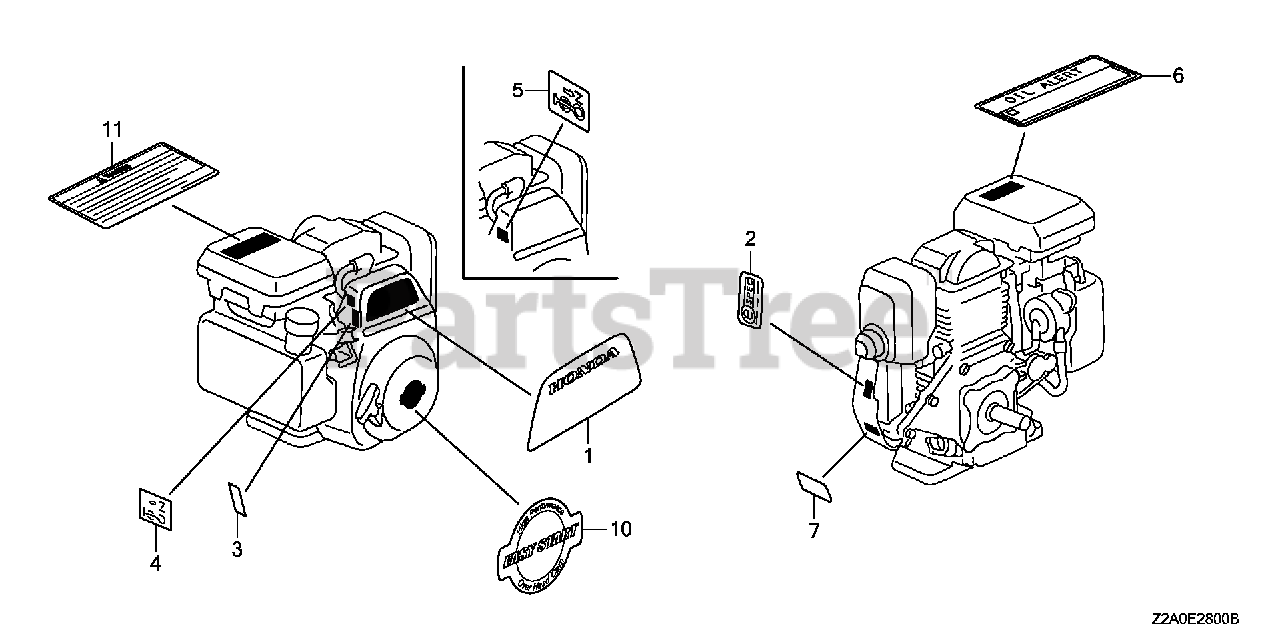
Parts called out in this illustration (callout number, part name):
1	MARK, EMBLEM (GS160)
5	MARK, CHOKE
7	LABEL, WARNING (NOT CERTIFIED FOR SALE)
10	MARK, RECOIL COVER
11	MARK, OPERATOR CAUTION (ENGLISH)
